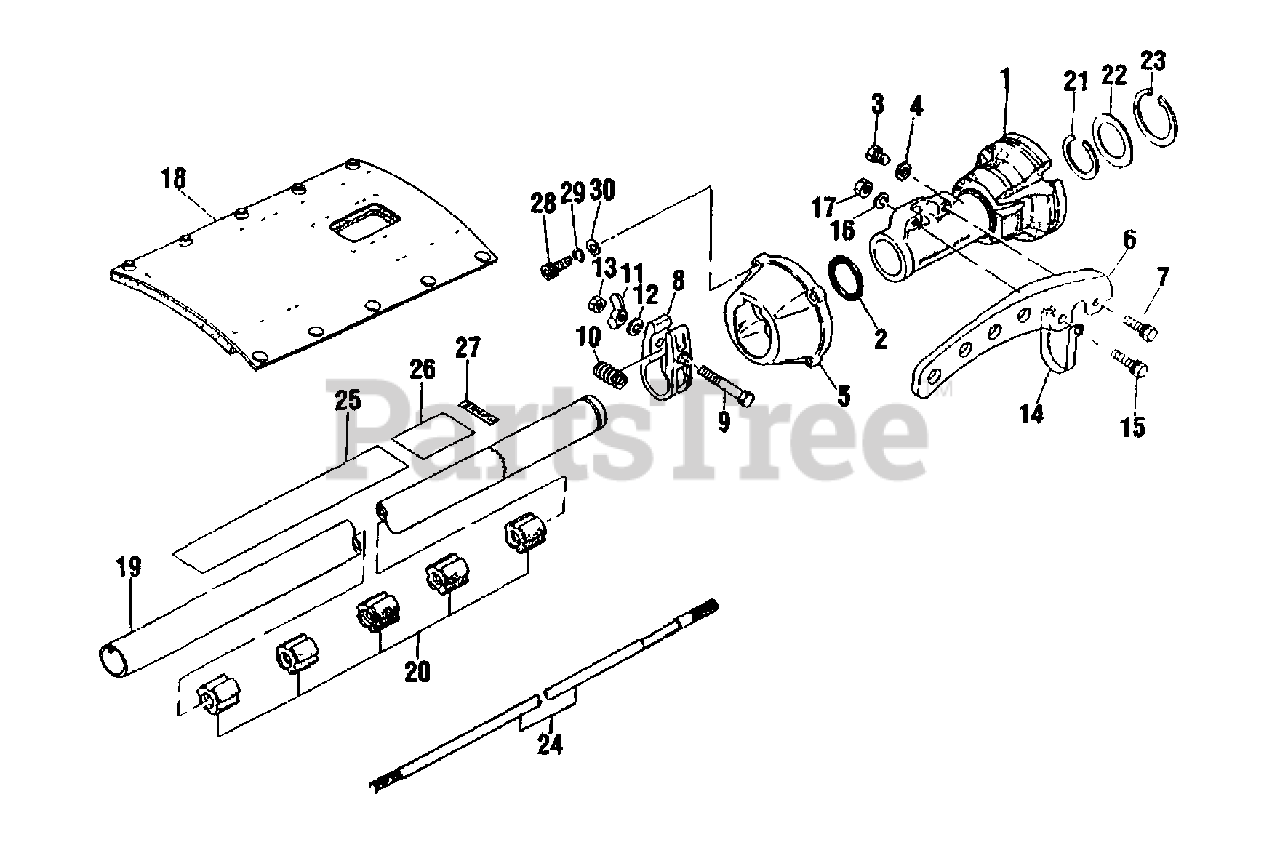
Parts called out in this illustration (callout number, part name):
1	CUSHION, AV
2	O-RING
3	BOLT M6×8
4	WASHER
5	CAP, CUSHION
7	BOLT
9	BOLT
10	SPRING
11	NUT, WING M6
12	WASHER 6 MM
13	NUT, LOCK M6
14	CLAMP
16	WASHER, SPRING 6
17	NUT, HEX M6
18	PROTECTOR
20	BUSHING
21	RING, SNAP
22	STOPPER
23	RING, SNAP Ø40
24	DRIVESHAFT
25	LABEL - MODEL
26	CAUTION PLATE
27	LABEL, HANDLE
28	BOLT 5×20
29	WASHER, SPRING 5
30	WASHER, FLAT 5.5×10×0.8
